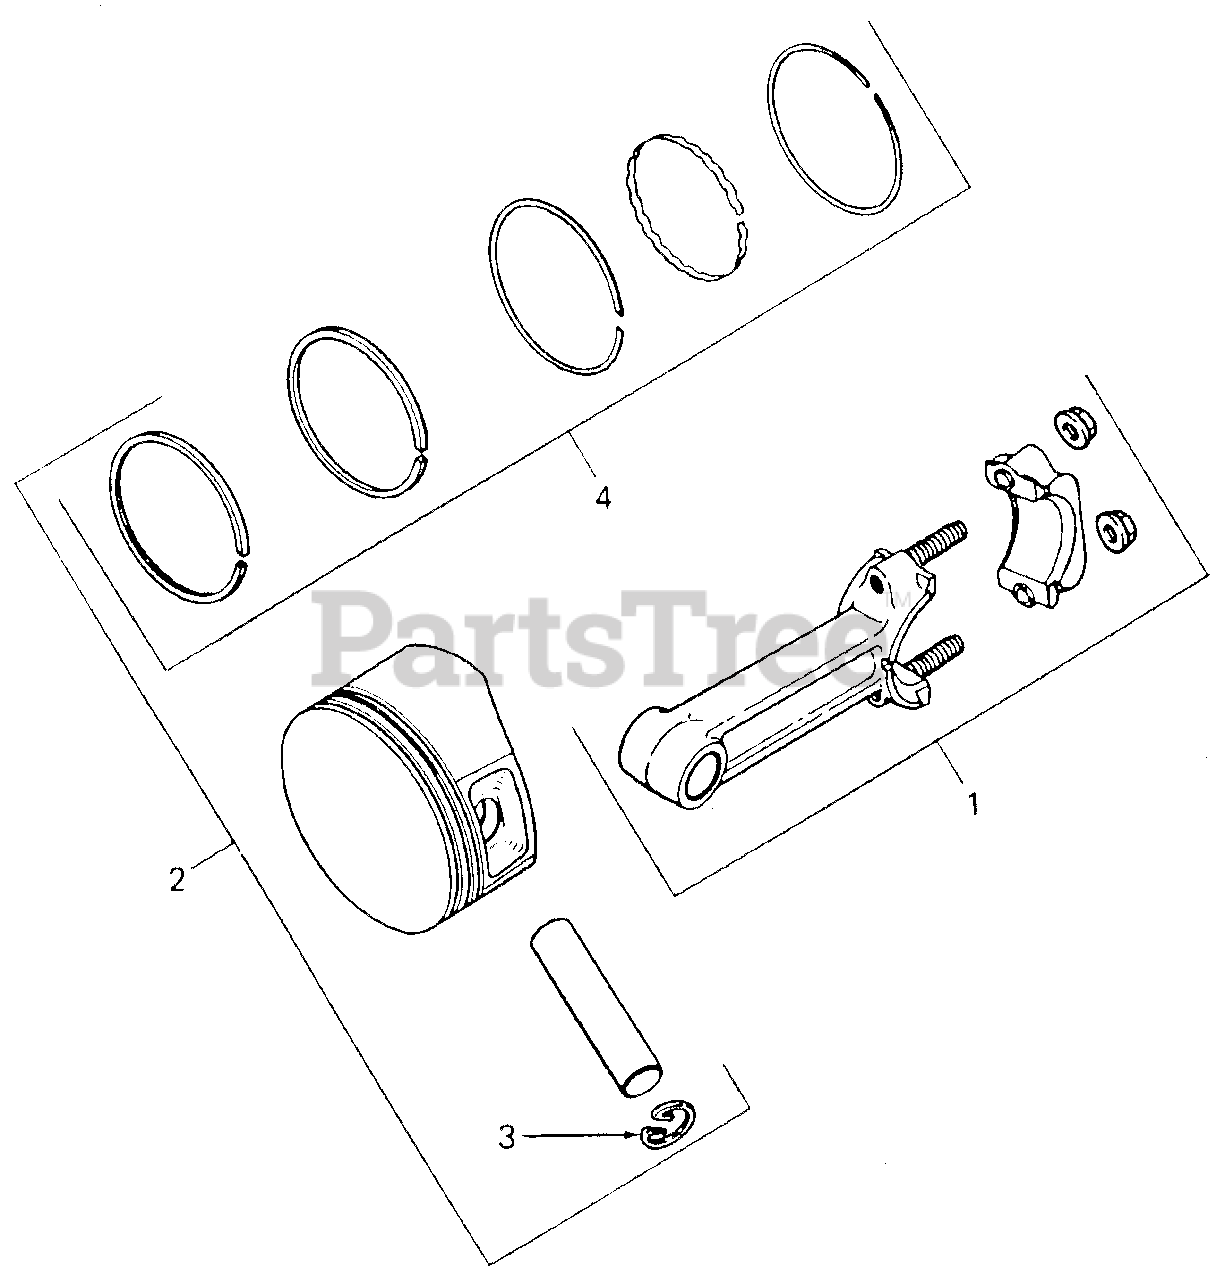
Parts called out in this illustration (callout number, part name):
1	Rod, Connecting (Std)
2	Piston w/Ring Set (Std)
3	Retain, Piston Pin
4	Ring Set (Std & .003)
